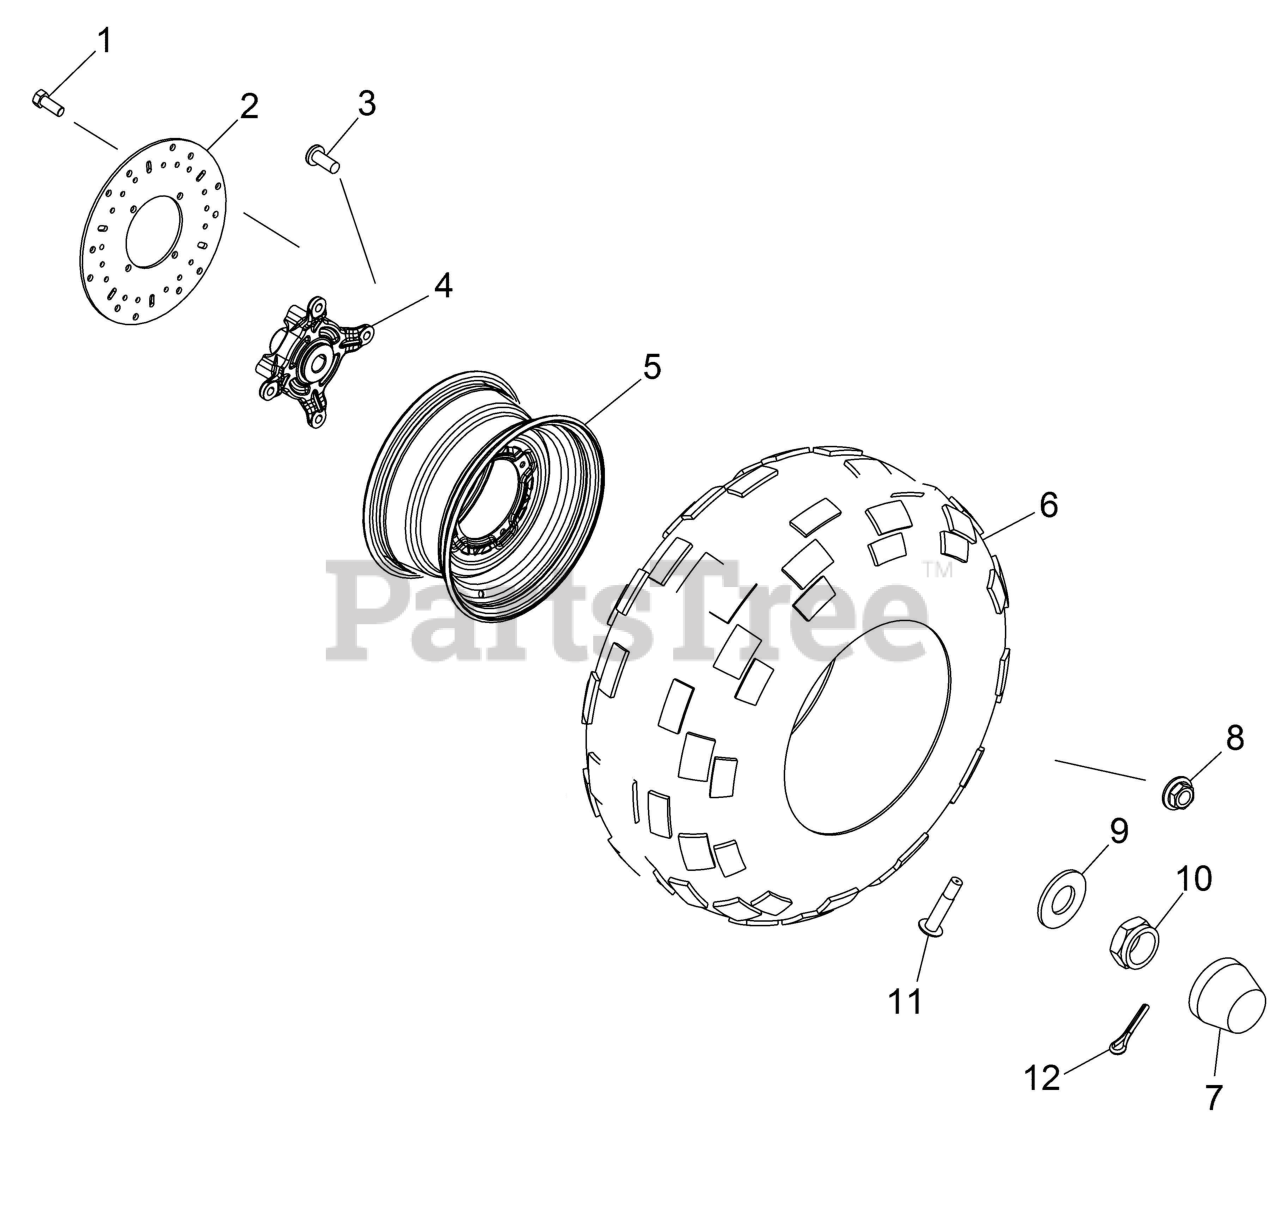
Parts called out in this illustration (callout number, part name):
1	SCR-M10X1.5X20 8.8 TXCS FL ZOD
2	DISC-BRAKE, FRONT
3	STUD-WHEEL,M12-1.5
4	HUB-WHEEL,FRONT(MACH),BLK
5	WELD-RIM,FR,10 GA,12X6,M.BLK
6	TIRE, FRONT, 25X10-12
7	HUB-DUST COVER,INTRNL LIP,BLNK
8	NUT-LUG,M12
9	WASHER, CONE
10	NUT-M18X1.5,CASTLE,ZINC/YELLOW
11	VALVE, RIM
12	PIN, COTTER
